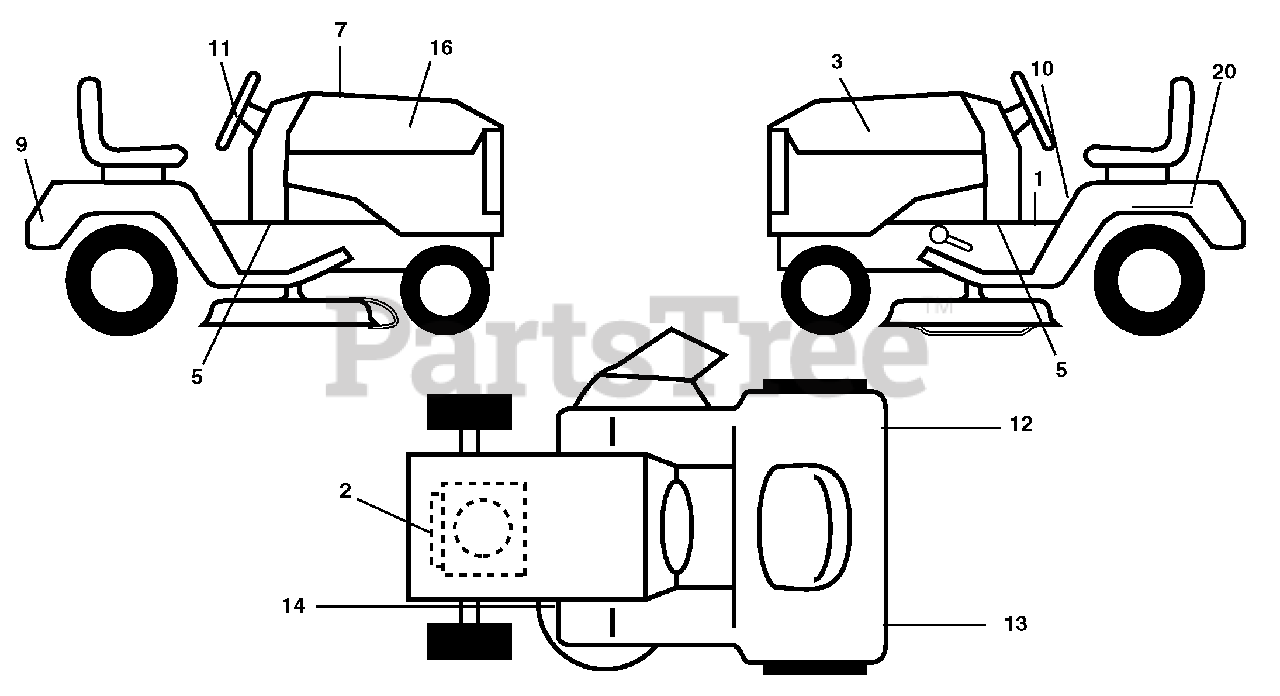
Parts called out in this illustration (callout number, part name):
1	Decal, Oper
2	Decal, Eng. HP
3	Decal, Hood LH
5	Decal, Lwr Dash
7	Decal, Replacement Parts
9	Decal, Fender Logo
10	Decal, Fender Danger E/F
11	Decal, Ins Strg Whl
12	Decal, Fend Reflector Rh
13	Decal, Fend Reflector Lh
14	Decal, V-Belt Schematic
16	Decal, Hood Rh
20	Decal, Bat Dan/Psn
20	Decal, Handle Lft Height Adjust
20	Decal, Bypass
20	Pad, Footrest LH
20	Pad, Footrest RH
20	Manual, Operator's E&S
20	Manual, Parts
